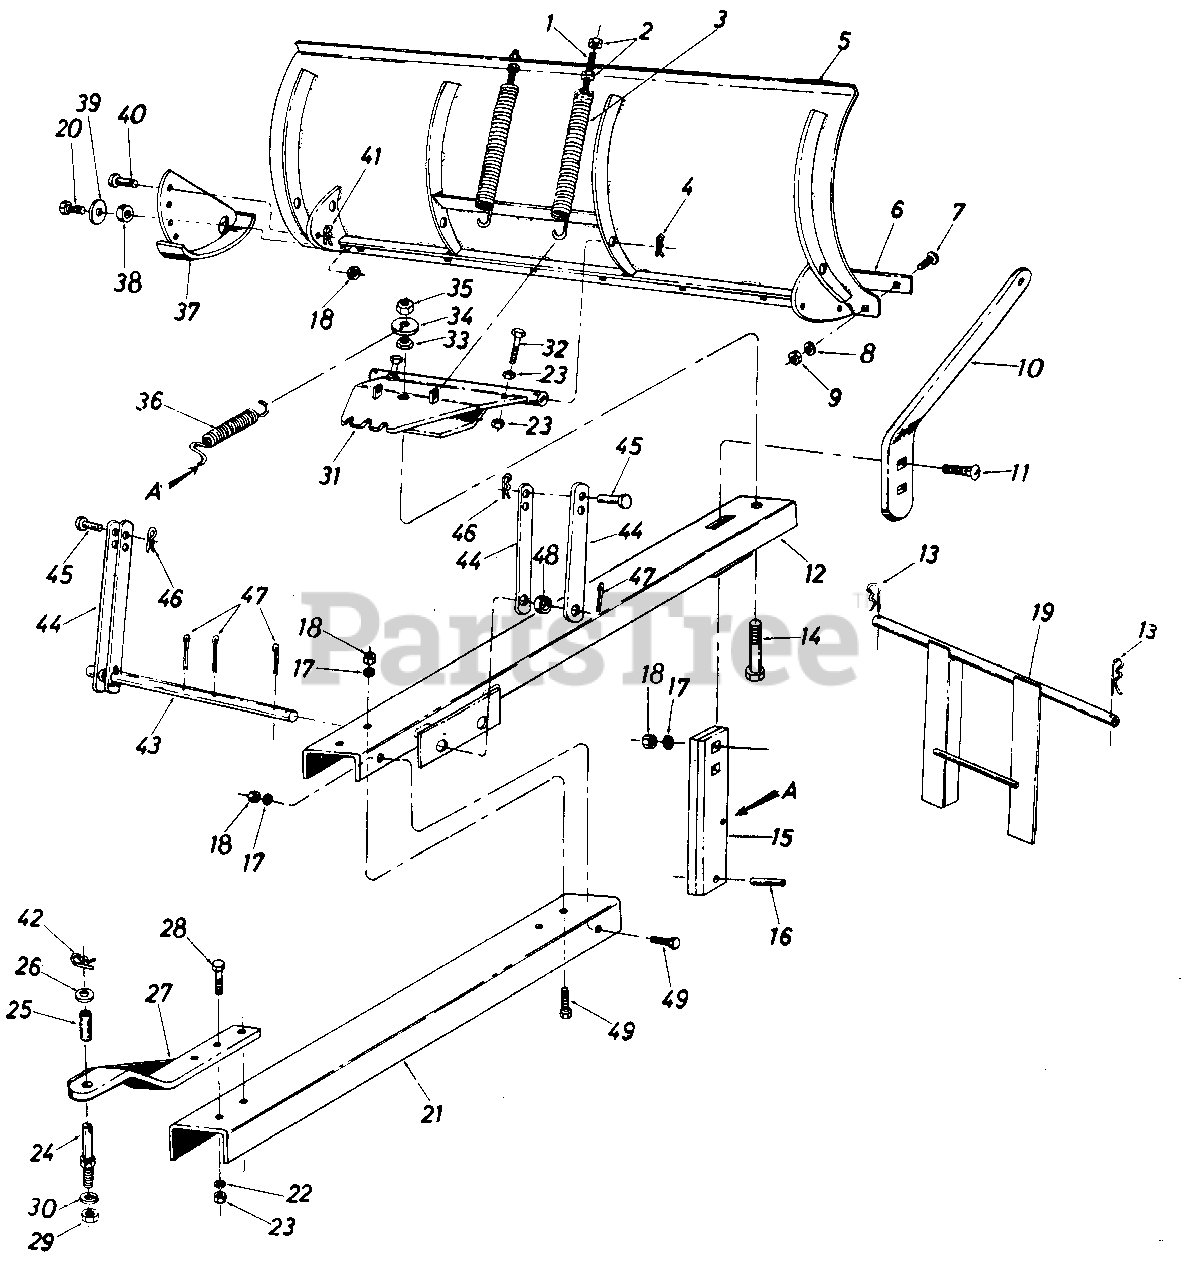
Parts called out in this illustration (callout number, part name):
1	Hex Scr. 3/8-16 x 4.50" Lg.*
2	Hex Nut 3/8-1 Thd.*
3	Blade Adjustment Spring
4	Hair Pin Cotter, 5/32
5	54" Blade Ass'y.
6	Wear Plate
7	Carriage Bolt 5/16-18 x .75" Lg.*
8	L.-Wash. 5/16" Scr.*
9	Hex Nut 5/16-18 Thd.*
10	Lock Extension Bar
11	Carriage Bolt 3/8-16 x 1.25" Lg.*
12	Front Push Bar Ass'y.
13	Hair Pin Cotter, 5/32
14	Hex Scr. 3/4-10 x 3.50" Lg.*
15	Angle - Lock Bar
16	Spring Pin Spirol .25" Dia. x 1.00" Lg.
17	L.-Wash. 3/8" Scr.*
18	Hex L.-Nut 3/8-16 Thd.*
19	Guide Bracket Ass'y.
20	Hex Scr. 3/8-16 x .75" Lg.*
21	Rear Push Bar Channel
22	L.-Wash. 1/2" Scr.*
23	Hex Nut 1/2-13 Thd.*
24	Link Clevis Pin
25	Spacer 1" O.D. x ?1/32" I.D. x .75" Lg.
26	Fl-Wash. 2-1/32 I.D. x .090 O.D.
29	Hex Jam L.-Nut 5,'8-18 Thd.
30	L.-Wash. 5/8" Scr.*
31	Pivot Plate Ass'y.
32	Hex Scr. 1/2-13 x 2.00" Lg.*
33	Hex Jam Nut 3/4-10 Thd.
34	Fl.-Wash. 3/8" ISpecial)
35	Hex Lock Nut 3/4-1 Thd.
36	Angle Lock Spring
37	Skid Assembly
38	Bushing, Pivot Skid
39	Fl.-Wash. .385" I.D. x 1.00" O.D.
40	Clevis Pin 5/16" Dia. x 3/4" Lg.
41	Hair Pin Cotter 3/32"
42	Hair Pin Cotter 5/32
43	Lift Shaft
44	Lift Link
45	Clevis Pin 1/2" Dia. x 1.00" Lg.
46	Hair Pin Cotter 3/32"
47	Cotter Pin 1/8" Dia. x 1.50," Lg.*
48	Spacer, Lift Link
49	Hex Scr. 3/8-16 x 1.00" Lg.*
